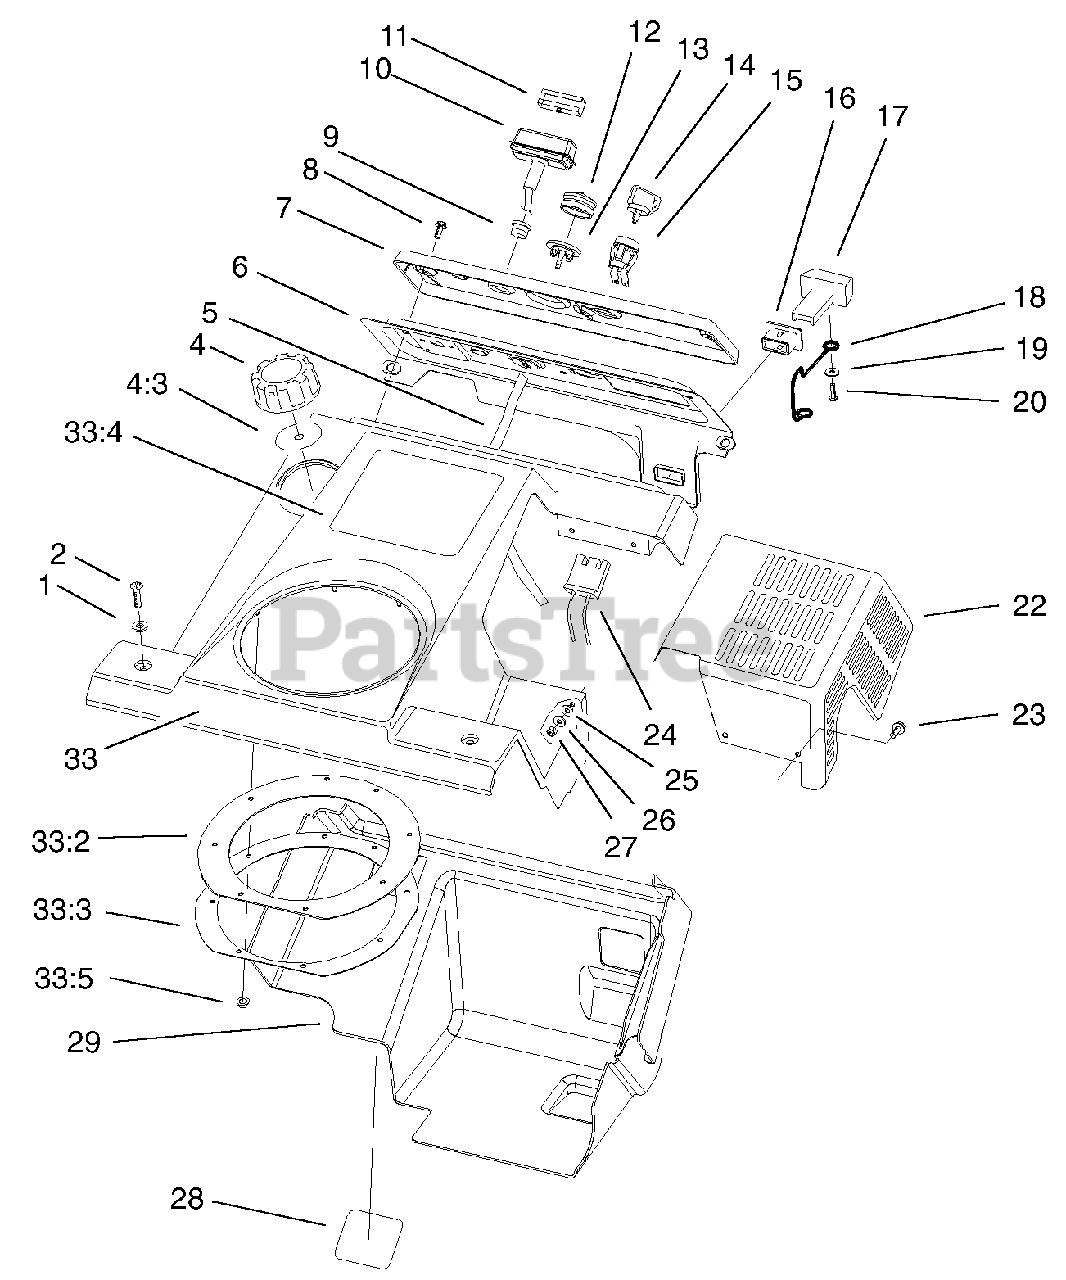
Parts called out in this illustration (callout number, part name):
1	WASHER-FLAT
2	SCREW-PPH
4	CAP-FUEL ASM
4:3	Gasket-Vented
5	HOSE-PRIMER
6	Panel-Control
8	SCREW-HWH
9	GUIDE-ROPE, STARTER
10	HANDLE-START
11	CLIP-STARTER
12	BULB-PRIMER
13	BODY-PRIMER
17	CONTROL-CHOKE
18	LINKAGE-CHOKE
19	WASHER-FLAT
20	SCREW-PPH
22	SHIELD-HEAT
23	SCREW-SHH
24	CONNECTOR-BODY
26	WASHER-FLAT
27	NUT-LOCK
33:3	RETAINER-SEAL, CHUTE
